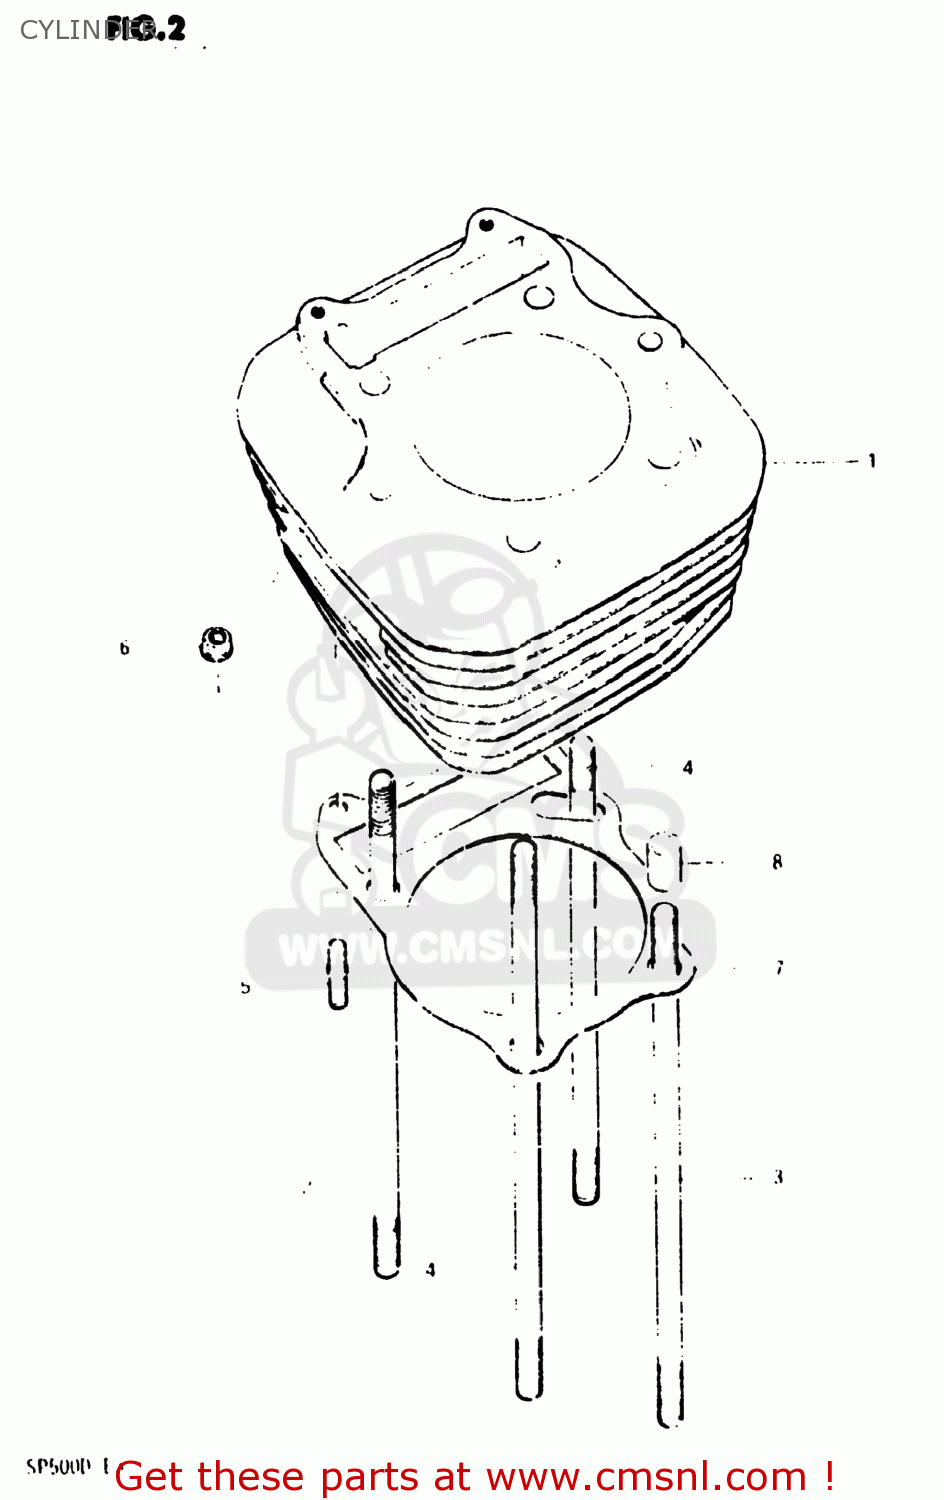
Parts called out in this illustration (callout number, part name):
1	CYLINDER
2	STUD
3	STUD
4	BOLT,STUD
5	STUD 6X25
6	NUT
7	GASKET,CYLINDER (NAS)
8	PIN
